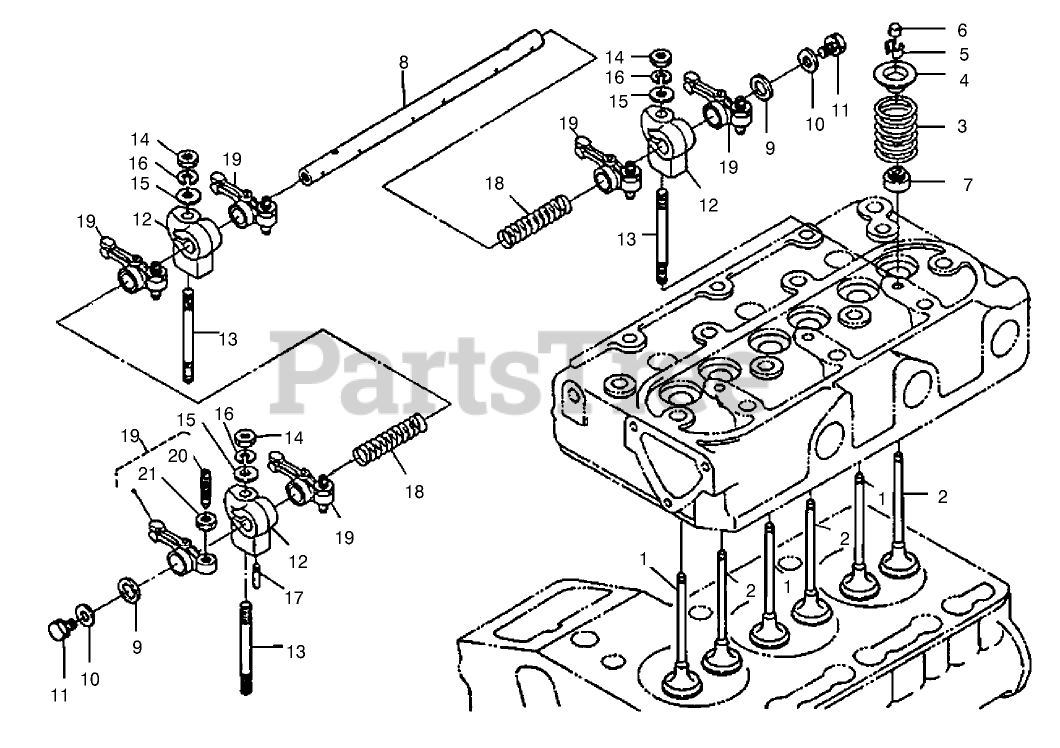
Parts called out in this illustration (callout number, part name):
1	VALVE-INLET
2	VALVE-EXHAUST
3	SPRING-VALVE
4	RETAINER-SPRING, VALVE
5	COLLET-SPRING, VALVE
6	CAP-VALVE
7	SEAL-STEM, VALVE
8	SHAFT-ARM, ROCKER
9	WASHER
10	WASHER-PLAIN
12	BRACKET-ARM, ROCKER
15	WASHER-PLAIN
16	WASHER-SPRING
17	PIN-SPRING
18	SPRING-ARM, ROCKER
19	ROCKER ARM ASM
20	SCREW-ADJUSTING
